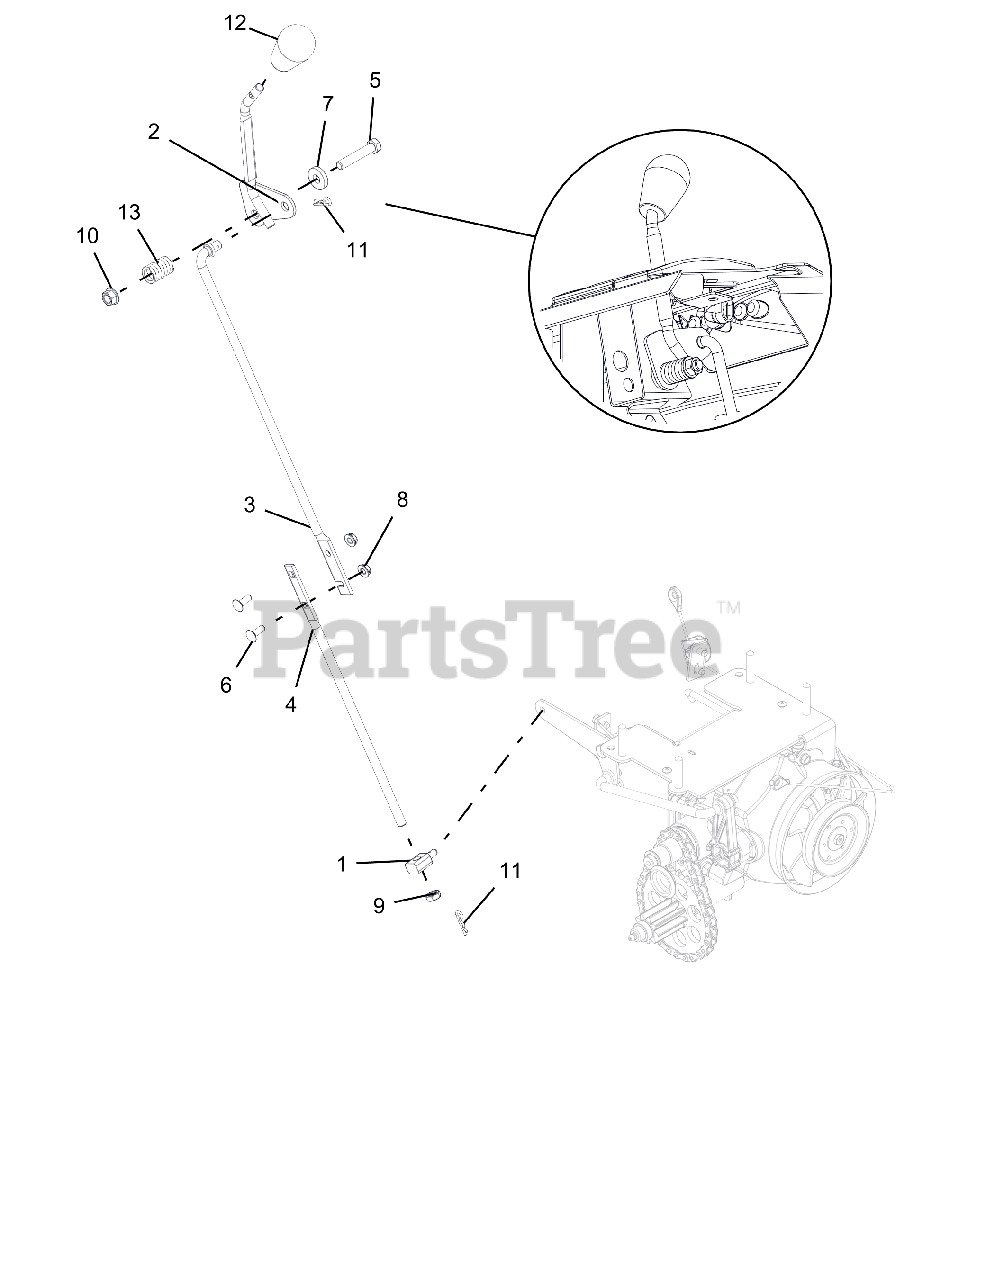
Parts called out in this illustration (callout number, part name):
1	PIVOT,SHIFT ROD .375-16(TRUNN)
2	WELDMENT, CONTROL LEVER(SHIFT)
3	ROD, SHIFT - UPPER
4	ROD. HYDRO SHIFT - LOWER
5	@BLT-HEX .38-16X2.00 GR5 YWZC
6	@BLT-RDHDSQNK .25-20X.75 G5YZ
7	WSHR-FL-STL .406X1.00X.188 YWZ
8	@NUT-LK-CTR-FLG .25-20 YWZC
9	NUT-HEX-JAM .375-16 YWZC
10	@NUT-LK-TOP-FLG .38-16 YWZC
11	PIN-HAIR INT .08X.18X1.18 YWZC
12	KNOB,SOFT TEARDROP,PUSH-ON GRY
13	SG-COMP .125X.781X1.250
